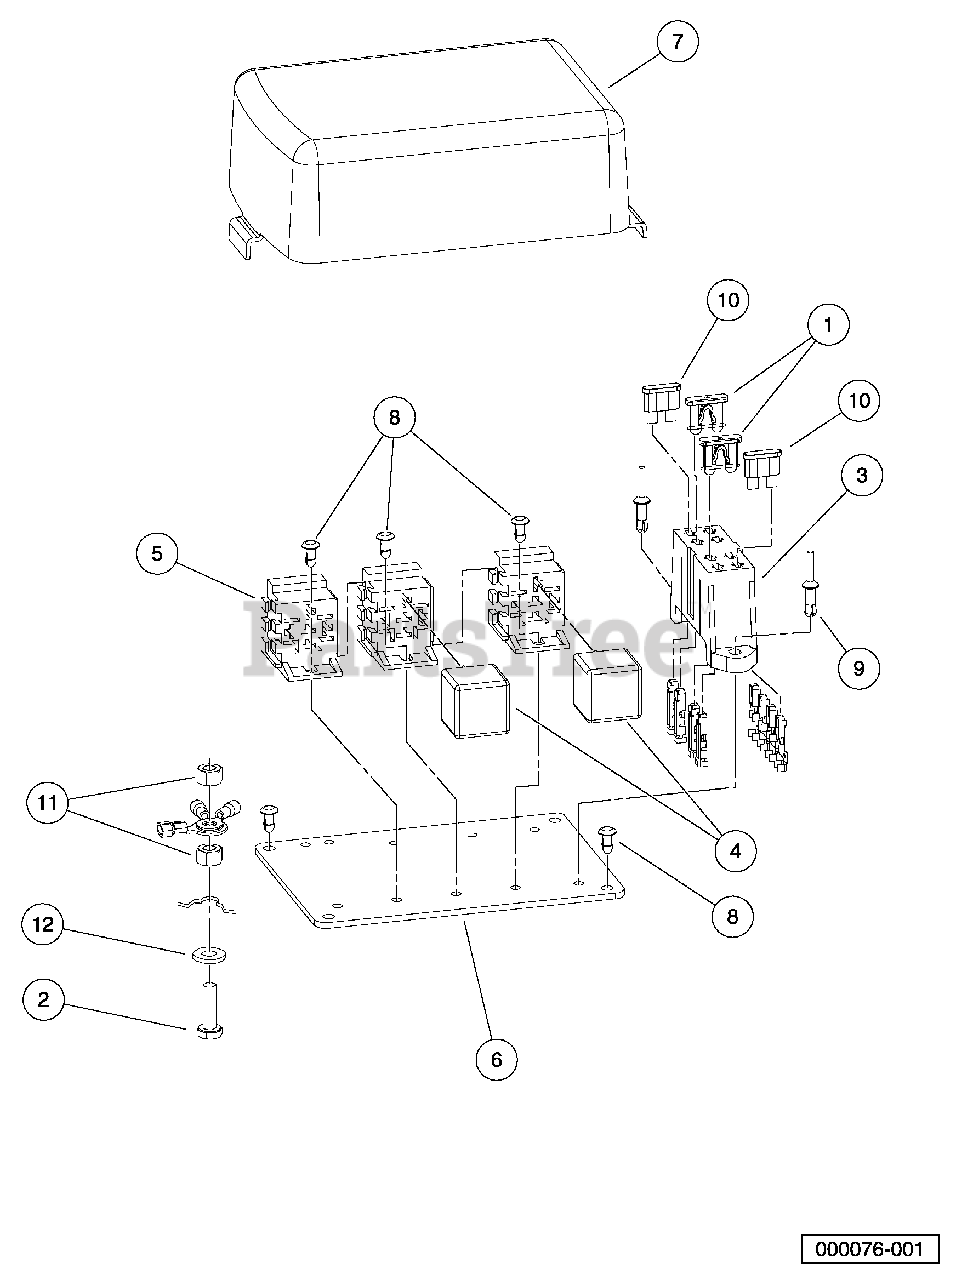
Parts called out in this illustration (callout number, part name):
1	Fuse, 10-Amp.
2	Screw, 1/4-20 X .88 Hex Hd Cap
3	Fuse Block
4	Relay, Mini ISO, SPDT
5	Connector, Relay.
6	Plate, Electrical
7	Cover, Electrical
8	Fastener, Push-in.
9	Rivet, Drive
10	Fuse, 25-Amp.
11	Locknut, 1/4-20 Dimpled
12	Washer, 1/4 Type A Narrow Flat
